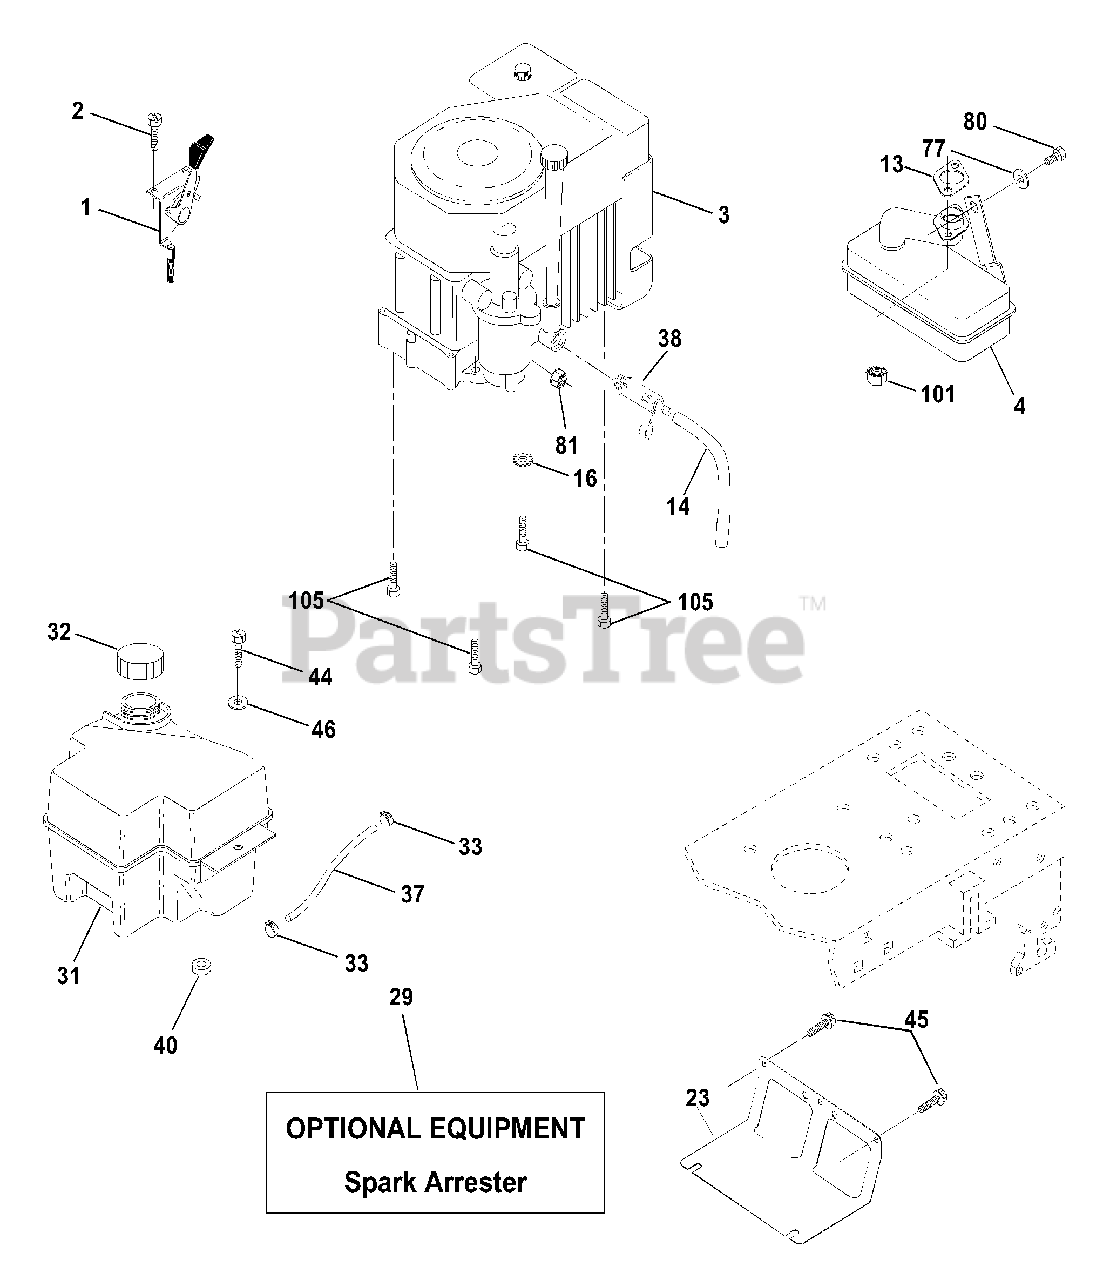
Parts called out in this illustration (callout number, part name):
1	Control Th/ch Flag
2	Screw Hex Thd Cut 1/4-20x5/8 T
4	Muffler
14	Tube Drain Oil Easy
16	Washer Lock Ext Tooth 3/8
23	Shield Brn/Dbr Guard
29	Kit Spark Arrestor (Flat Scrn)
31	Tank Fuel Front
32	Cap Asm Fuel W/sym Vented
33	Clamp Hose Black
37	Line Fuel 20"
38	Plug Drain Oil Easy
40	Bushing Snap Nyl Blk Fuel Line
44	Screw Hexwsh Thdrol 1/4-20x3/4
45	Screw Hexwsh Thdr 3/8-16 x 3/4
46	Washer 9/32 X 7/8 X 16 Ga
77	Washer 5/16 x 3/4 x 16 Ga.
80	Bolt Hex Hd 5/16-18 Unc x 1/2
81	Nut Keps Hex 1/4-20 UNC
101	Nut Flange M8-1.25
105	Screw 3/8-16 x 1
